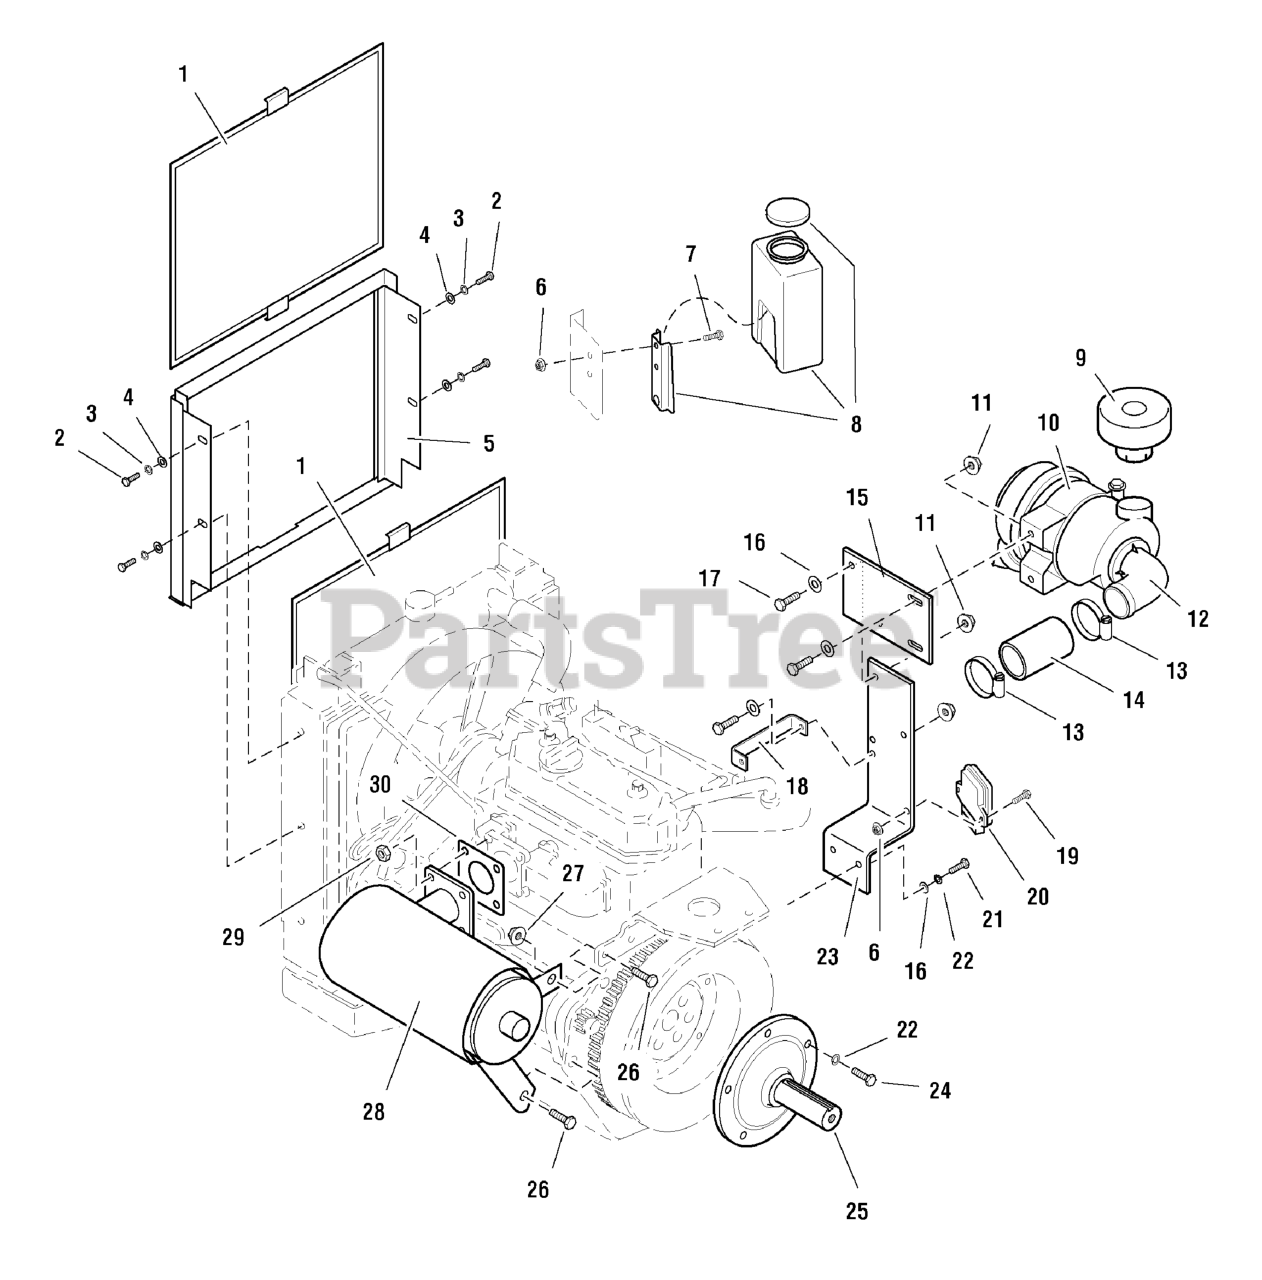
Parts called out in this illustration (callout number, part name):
1	SCREEN
3	WASHER, 1/4 LOCK
4	WASHER, 1/4 SAE
5	RADIATOR SHROUD
6	NUT, 1/4-20 HEX SERR. FLANGE
7	BOLT, 1/4-20 x 3/4
8	RADIATOR & OVERFLOW KIT
9	RAIN COVER
11	NUT, 5/16-18 HEX SERRATED FLANGE (SMALL)
13	HOSE CLAMP
15	AIR CLEANER MOUNT PLATE
16	WASHER, 5/16" SAE
17	BOLT, 5/16-18 X 3/4 GD5
18	AIR CLEANER BRACE
19	BOLT, 1/4-20 X 1" GD5 CZ
20	IGNITION MODULE
21	BOLT, M8 x 35MM
22	WASHER, 5/16 LOCK CZ
23	AIR CLEANER BRACKET
24	BOLT, M8 x 20MM
25	STUB SHAFT
26	BOLT, 3/8-16 X 1" GD5 CZ
27	NUT, 3/8-16 Hex Serrated Flange
28	MUFFLER
30	MUFFLER GASKET
